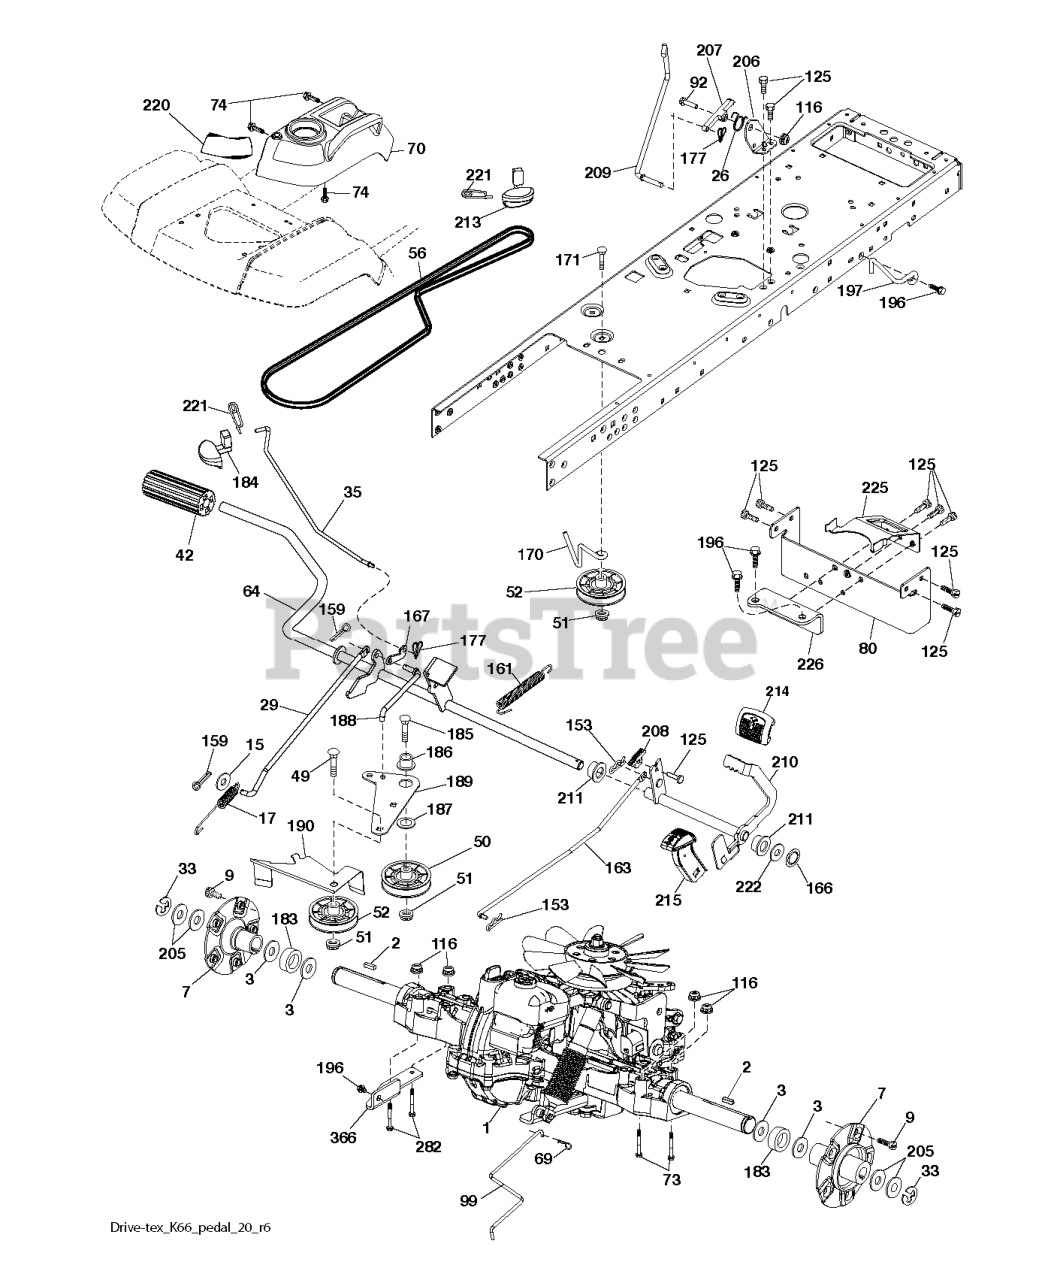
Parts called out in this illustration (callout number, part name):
2	KEY, 1/4 SQ X 1 1/4
7	HUB.PNT.GT.PM.1IN.AXLE.E-DIP
15	WASHER PLAIN WASHER 3/8 X 0.08
17	SPRING.BRAKE.K46
26	SPRING.RETURN.CRUISE
29	ROD.BRAKE.K66
33	E RING HYT
35	ROD ROD.PARKINGBRAKE.GT.HUSQ/P
42	PEDAL COVER
50	IDLER.FLAT.910.OFFSET
51	NUT LOCK FLG 3/8-16 UNC
52	IDLER.V-GROOVE.910.OFFSET
56	BELT.DRIVE.T2.K66
64	SHAFT.ASM.PEDAL.BRK.CNTR
69	HAIRPIN.SOFT.ZINC.059X1.125
70	CONSOLE.ASM.RH.GT.FC.HUSQ
80	STRAP.PNT.TORQUE.K66.EDIP
99	ROD.BYPASS.K66
125	SCREW
153	RETAINER M
161	SPRING, RETURN LT
163	ROD.PEDAL.CONTROL
166	NUT.PUSH.625
167	LATCH.BRAKE.SPRING
170	KEEPER.V-IDLER.CENTER.
177	PIN COTTER;LOCKING;BOWTIE;1IN
183	SPACER.SPLIT.1.000IDX1.75
184	HANDLE.PARKING.BRAKE.H (BLK)
186	SPACER.RETAINER
188	LINK.CLUTCH.GROUND DRIVE.LONG
189	BELLCRANK.GROUND.DRIVE.TEX.
190	KEEPER.BELLCRANK.DRIVE
196	SCREW 3/8-16X1
206	BRACKET.MOUNT.CRUISE.LATCH
209	ROD ROD.CRUISECONTROL.GT.HUSQ/
210	ROCKER.ASM.PEDAL.CONTR
211	BEARING.NYLON
213	KNOB.CONTROL.CRUSIE.HU
214	PEDAL.FORWARD.PAD.TEX
215	PEDAL.COVER.REVERSE.CRD.X428BK
220	REFLECTOR.RH.TEX GT
221	RETAINER.SPRING.CLIP.H
222	WASHER 21/32 X 1-1/4 X 10 GA.
225	KEEPER.BELT.TRANSAXLE.K66
226	BRACKET.MOUNT.TORQUE.K66.TG
282	BOLT HEX FLGHD 5/16-18X3 GR. 5
366	BRACKET ASSEMBLY REINFORCEMENT
